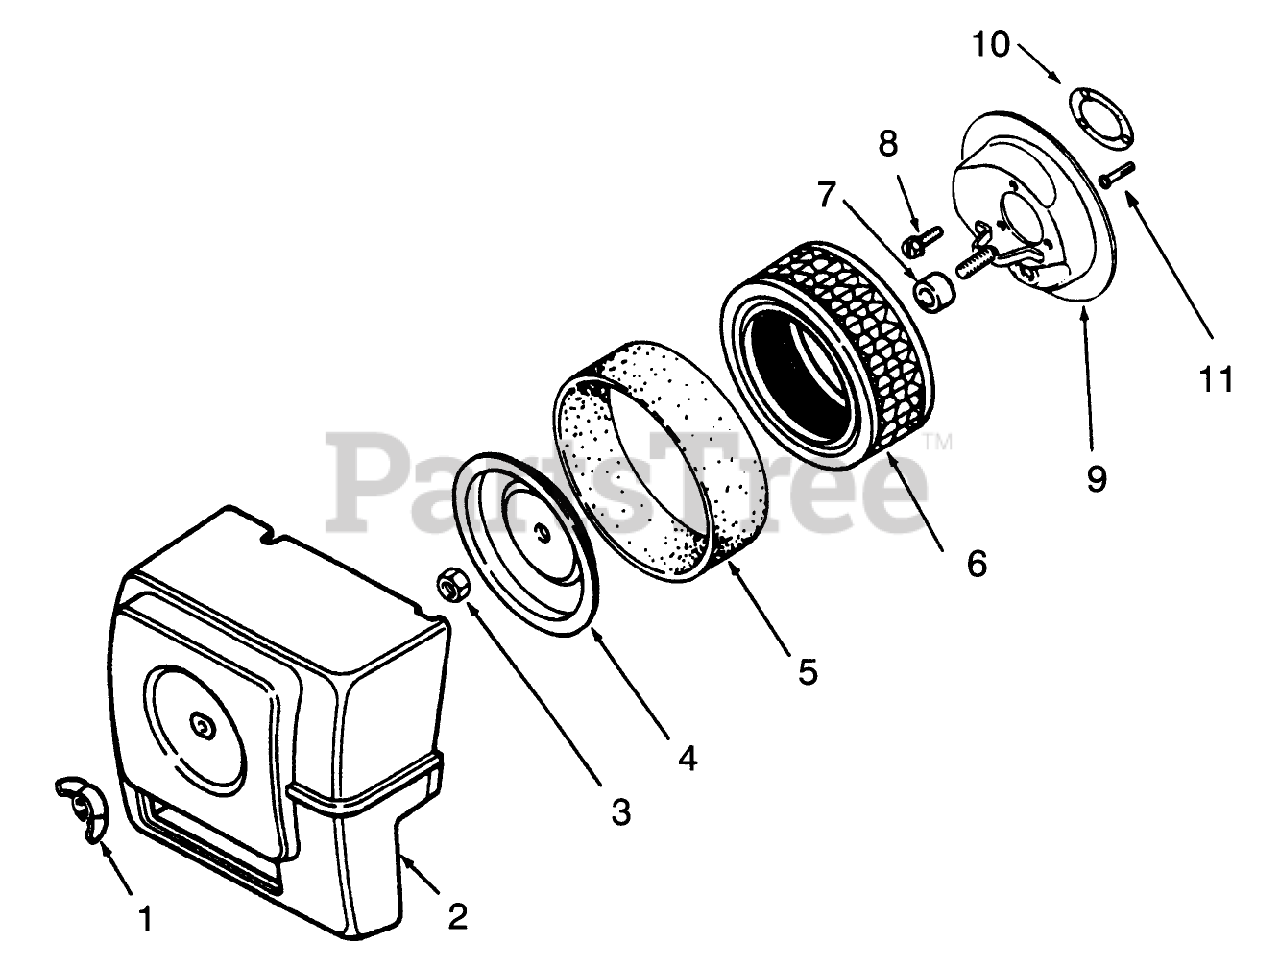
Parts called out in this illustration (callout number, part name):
1	KOHLER X-276-7
2	KOHLER 47-096-10
3	KOHLER 41-100-04
4	KOHLER 52-082-04
5	KOHLER45-083-01
6	KOHLER 45-083-02
7	KOHLER 231032
8	KOHLER X-67-65
9	KOHLER 47-094-20
10	KOHLER 45-041-07
11	KOHLER X-770-1
